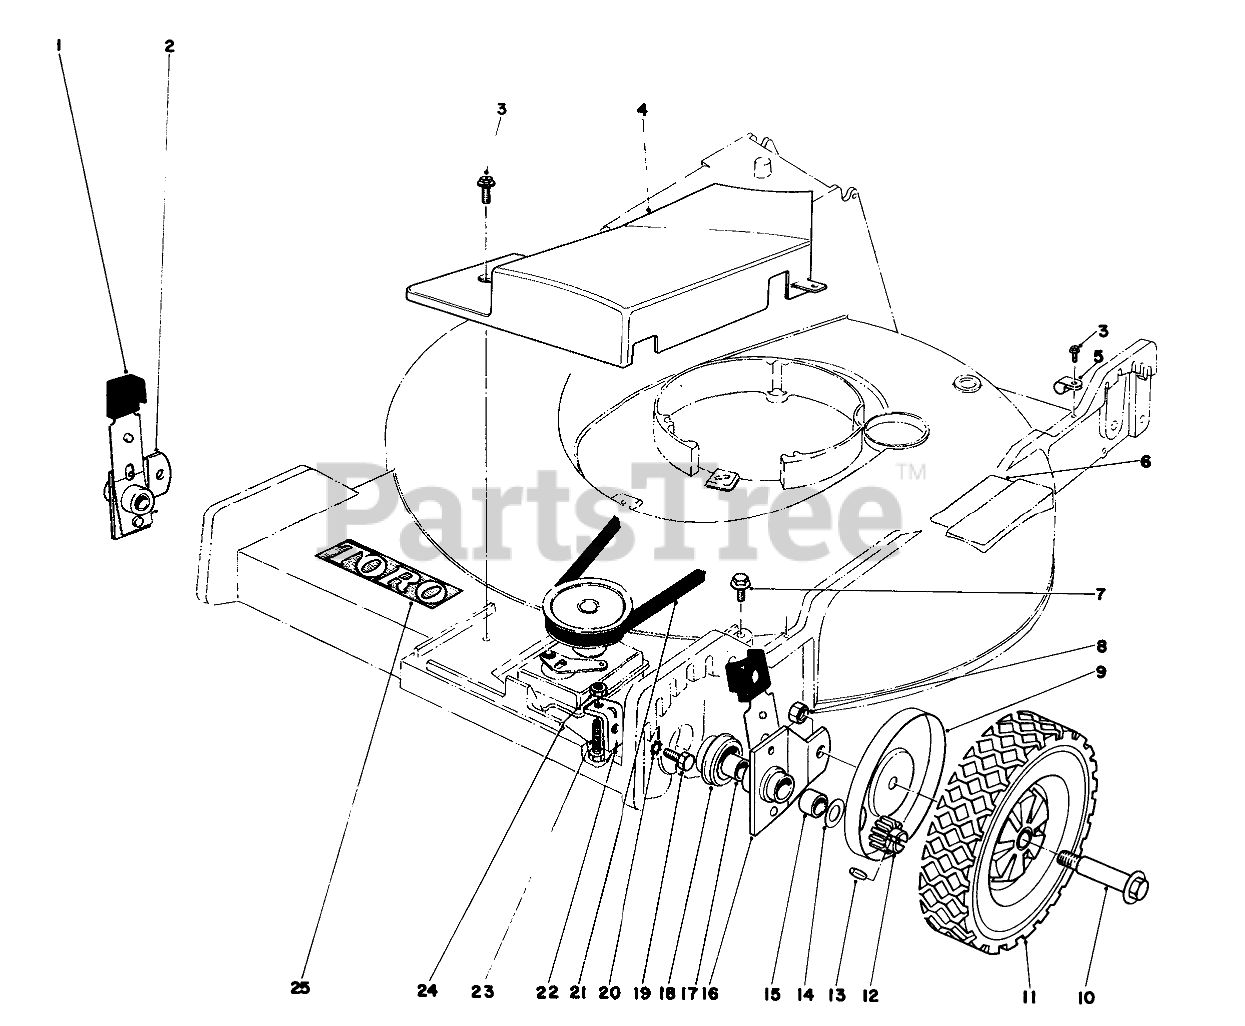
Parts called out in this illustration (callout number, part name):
1	KNOB-ARM
2	Pivot Arm R.H. (Incl. Ref. #15 & 17)
3	SCREW
4	BELT COVER
5	CLAMP-NYLON
6	Decal Place Foot Here
7	SCREW-HWHTF
8	Nut
9	WHEEL COVER
10	BOLT-WHEEL
11	Wheel & Tire Assembly
12	Pinion
13	Pin
14	WASHER-THRUST
15	Bushing
16	Pivot Arm L.H. (Incl. Ref. #15 & 17)
17	Bushing
18	END CAP
19	SCREW-HH
20	WASHER-LOCK
21	V-BELT
22	Bracket-Gear Box
23	SCREW
24	NUT-LOCK
25	Decal-Toro
